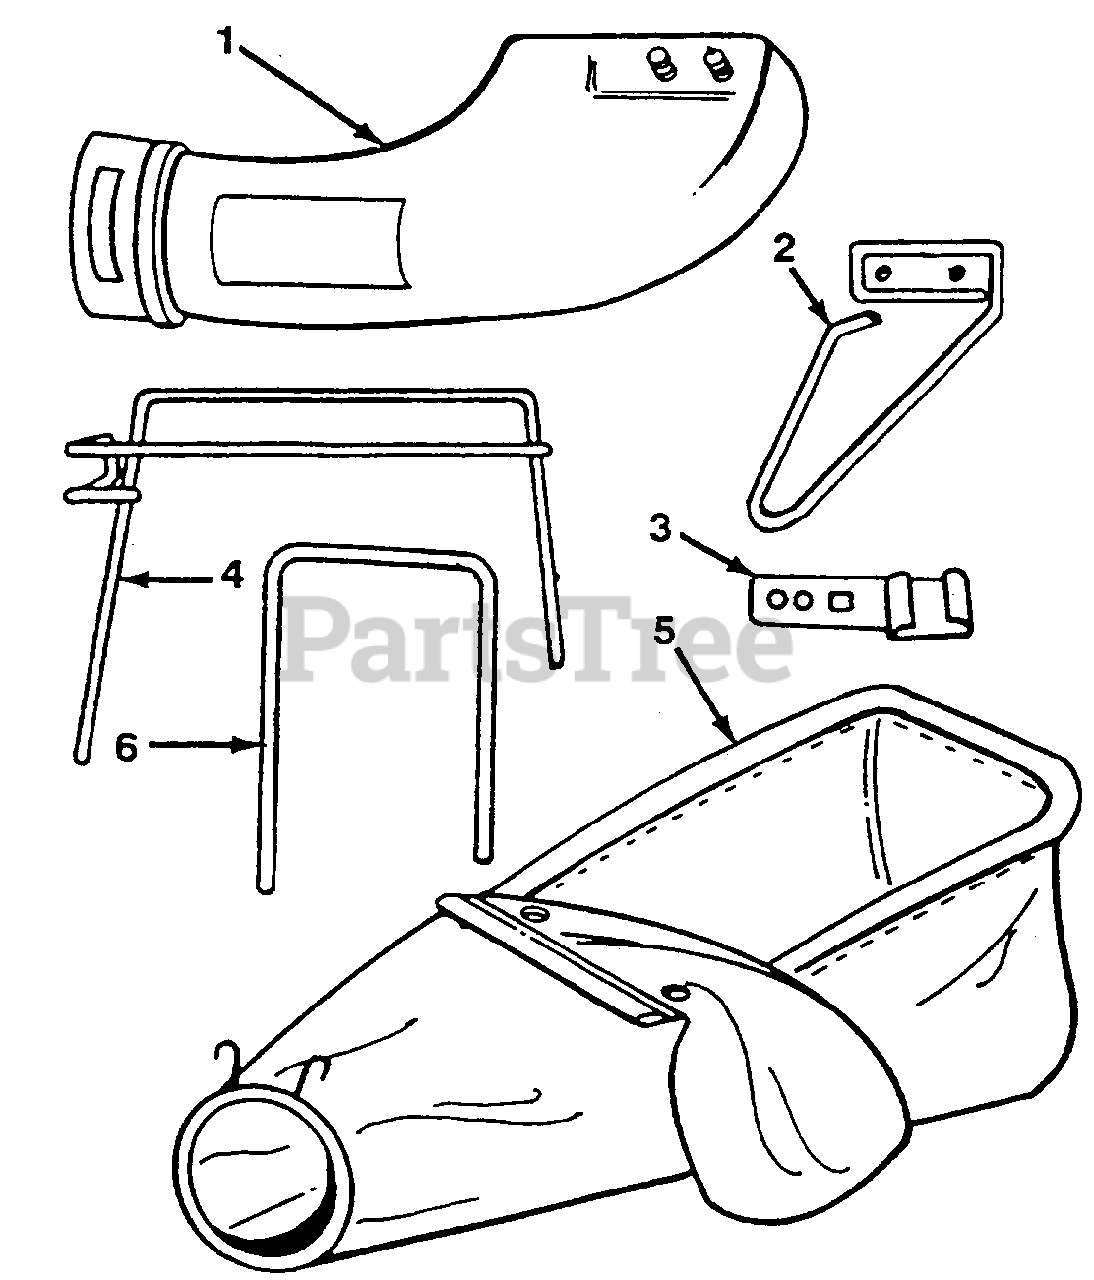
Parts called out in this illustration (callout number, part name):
1	Plastic Chute
2	Chute Mounting Bracket w/Wire
3	Handle Bracket
4	Bag Frame
5	Bag w/Clamp Ring
6	Upper Support Tube
